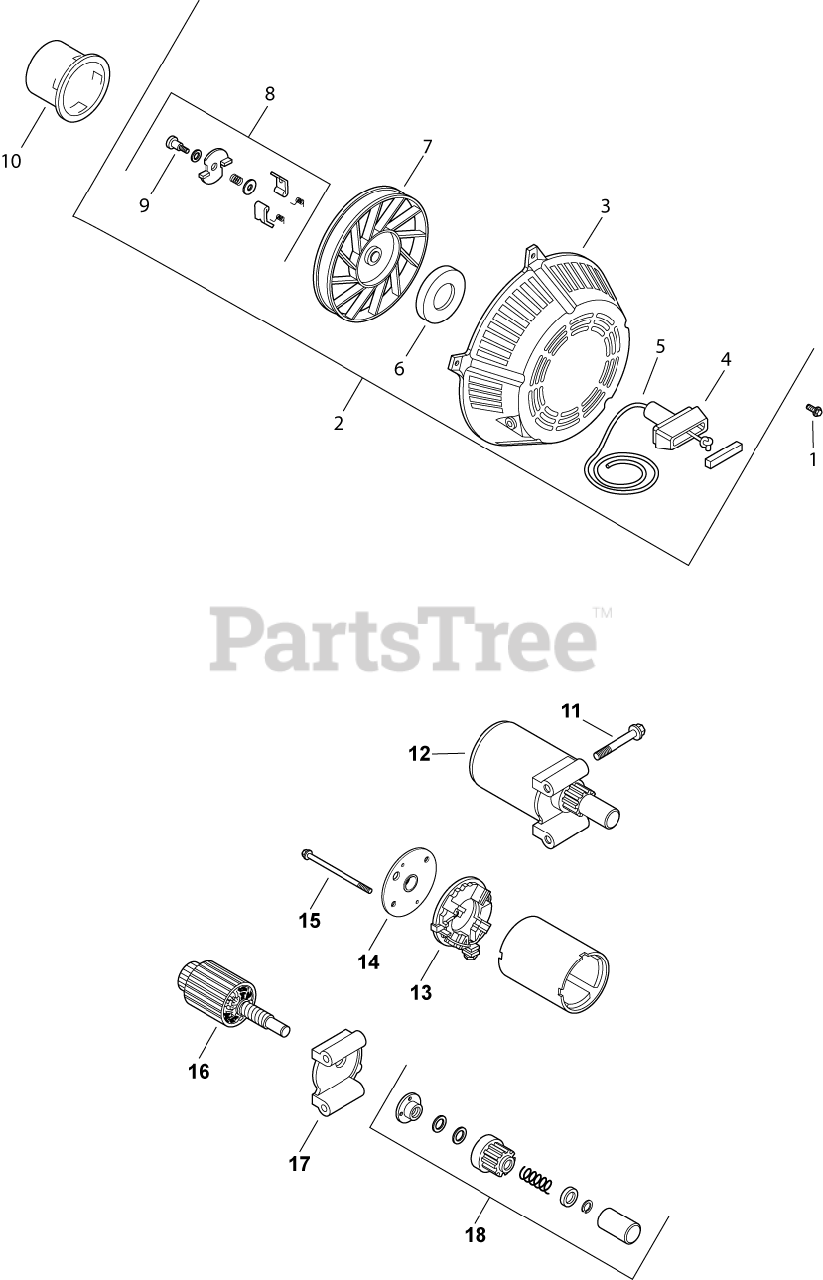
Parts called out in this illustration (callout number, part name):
1	SCREW, HVY FLG M5X.8X10
2	STARTER ASSY,RETRACTABLE-USE 12 165 03-S
3	HOUSING - DISCONTINUED
4	HANDLE, RECOIL STARTER
5	ROPE - DISCONTINUED
6	SPRING & KEEPER - (#DSC)
7	PULLEY - (#DSC)
8	KIT, DOG REPAIR - (#DSC)
9	SCREW - DISCONTINUED
11	SCREW, FLG M8X1.25X70
12	ELECTRIC STARTER-BENDIX DRIVE
13	BRUSH KIT - (#DSC)
14	CAP - DISCONTINUED
15	BOLT, THRU #10-24X4 13/32" - DISCONTINUED
16	ARMATURE - DISCONTINUED
17	CAP, DRIVE END - (#DSC)
18	KIT, DRIVE
